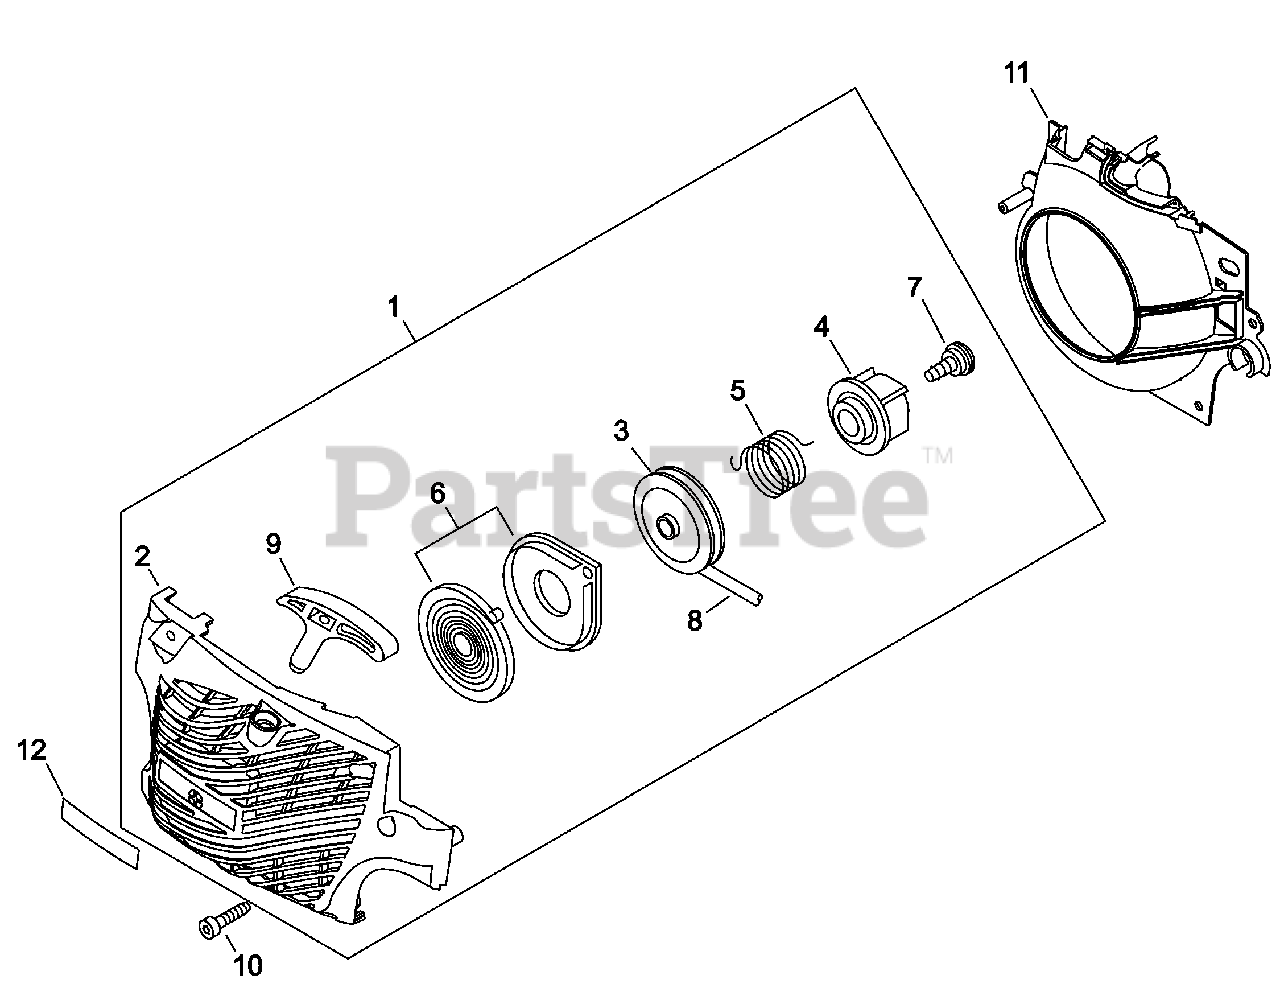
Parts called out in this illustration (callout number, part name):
1	STARTER ASSY, RECOIL
2	CASE, STARTER
3	REEL, ROPE
4	PAWL CATCHER
5	SPRING, TORSION
6	SPRING KIT, RECOIL
7	SCREW
8	ROPE, STARTER 3.5×900
9	GRIP, STARTER
10	BOLT, TORX 5×20
11	COVER, FAN
12	LABEL, ECHO
